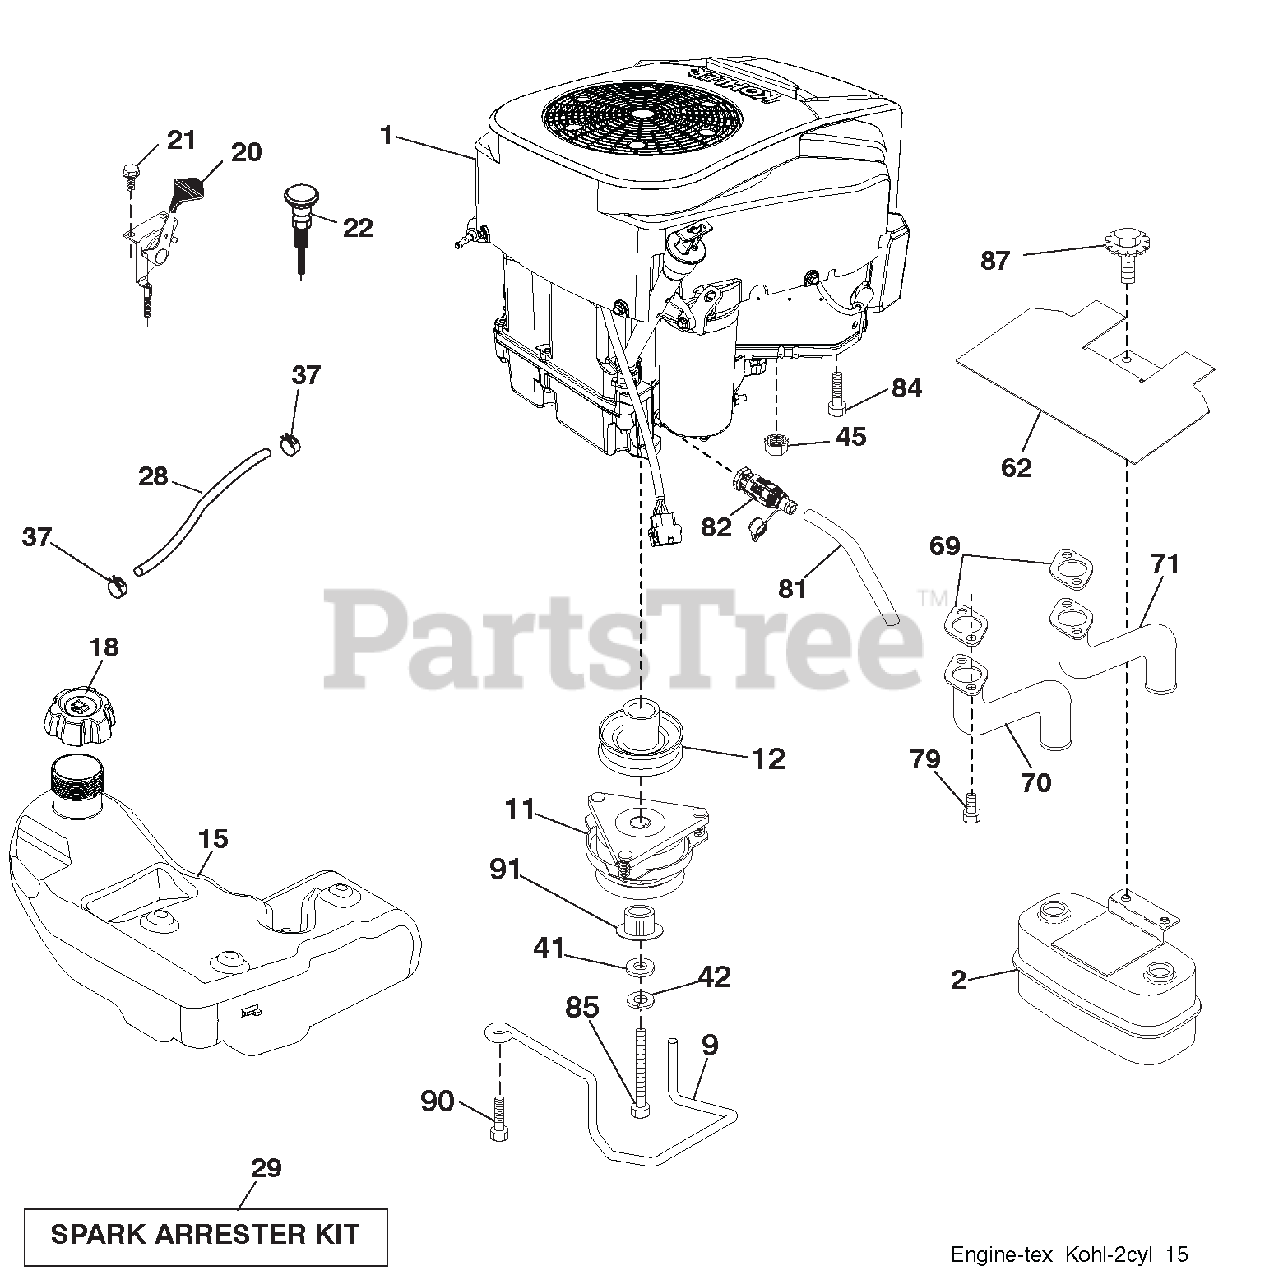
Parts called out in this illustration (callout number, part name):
2	MUFFLER ASM.TWIN.LO-TONE
9	KEEPER.BELT.ENGINE.4.25"NSTG
11	CLUTCH.ELECTRIC.LT.1"CRANK
12	PULLEY.ENGINE.TUFFTORQE.1"CRK.
15	TANK.FUEL
18	CAP FUEL
20	CONTROL.THROTTLE
22	CONTROL CHOKE
28	LINE.FUEL.20"
29	KIT.SPARK ARRESTOR(392390 B&S)
37	CLAMP.HOSE.BLK.
41	WASHER.1-1/2 ODX15/32 IDX.250
42	WASHER.LOCK.HVY HLCL.SPR.7/16
45	Nut, Keps Hex 1/4-20 unc
62	SHIELD.HEAT.MUFFLER.
70	PIPE.EXHAUST.LH.CV18/20
71	PIPE.EXHAUST.RH.CV18/20
79	SCREW.SOCKET HD.5/16-18 X .75
81	TUBE.DRAIN.OIL.EASY
82	VALVE OIL DRAIN
84	SCREW.3/8-16 X 1.SMGML.TAP/R
85	BOLT.HEX.7/16-20 X 3.75 X GR.
87	BOLT.5/16-18UNCX3/4 W/SEMS.BLK
90	SCREW.3/8-16X1.SMGML.TAP/R.BLK
91	BUSHING.1.375OD.HEYCO 2210
